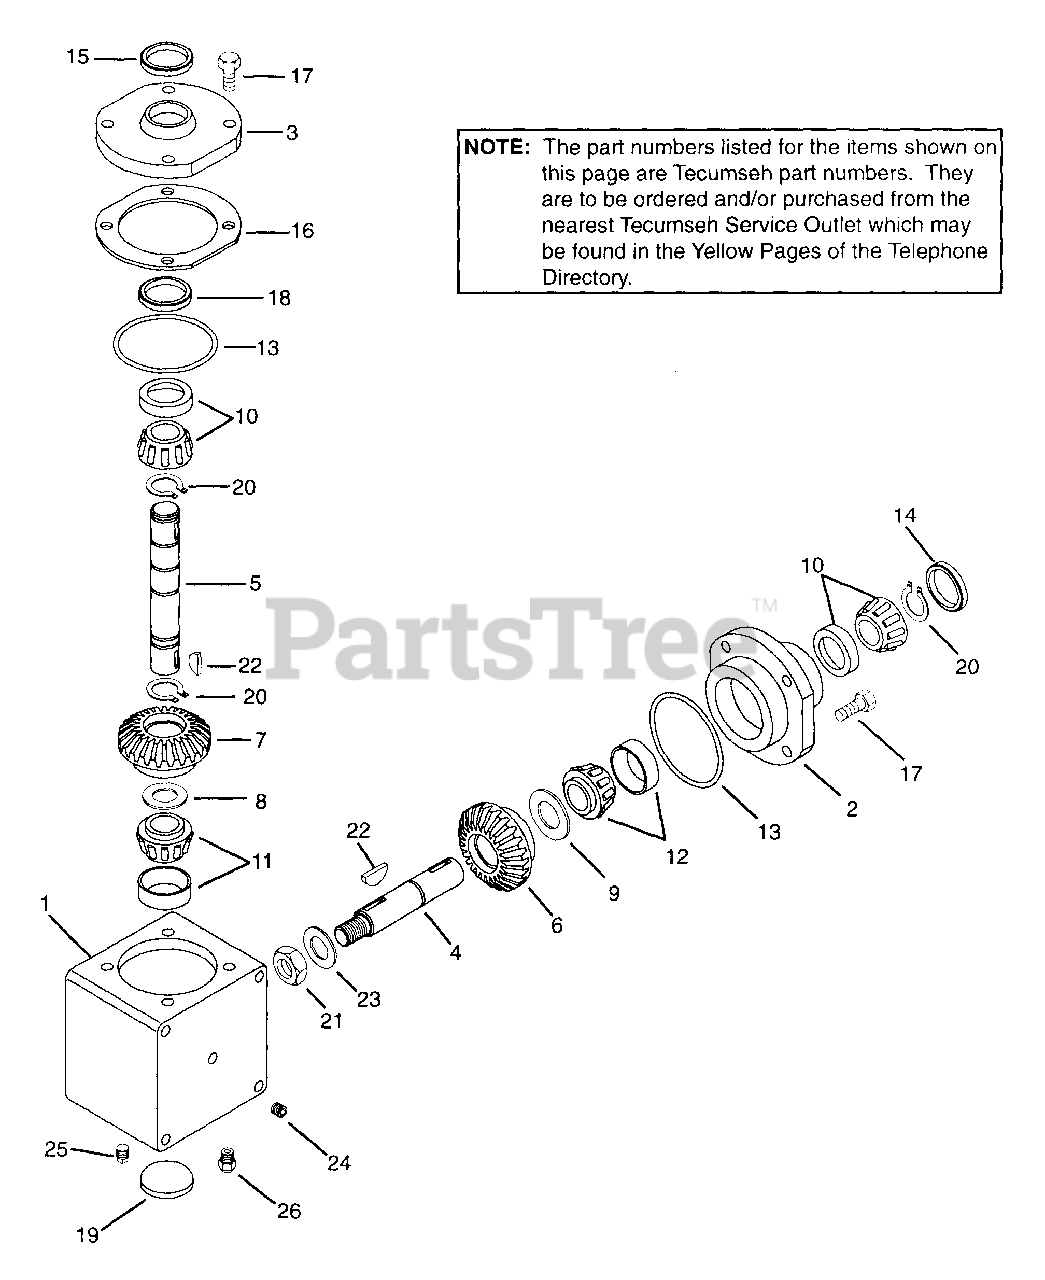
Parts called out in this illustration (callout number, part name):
1	Housing, Right Angle Drive
2	Cap, Retainer
3	Cap, Retainer
4	Shaft, Input (5.38" long)
5	Shaft, Output (7.89" long)
6	Gear, Spiral Bevel (25 teeth)
7	Gear, Spiral Bevel (26 teeth)
8	Shim (1-1/2" O.D. x 1-1/64" I.D. x .002 thick)
9	Shim (2.000" O.D. x 1.531" I.D. x .002 thick)
10	Bearing & Cup Assembly.
11	Bearing & Cup Assembly.
12	Bearing & Cup Assembly.
13	"O" Ring
14	Seal, Oil
15	Seal, Oil
16	Shim, Cap Retainer
17	Screw, Hex, HD. Sems, 5/16-18 x 1
18	Ring Load
20	Ring, Retaining
21	Jam, Nut 3/4-16
22	Key, Woodruff
23	Washer, Flat 1
24	Plug, Pipe 14-18
25	Plug, Pipe 1/8-27
26	Valve, Relief
